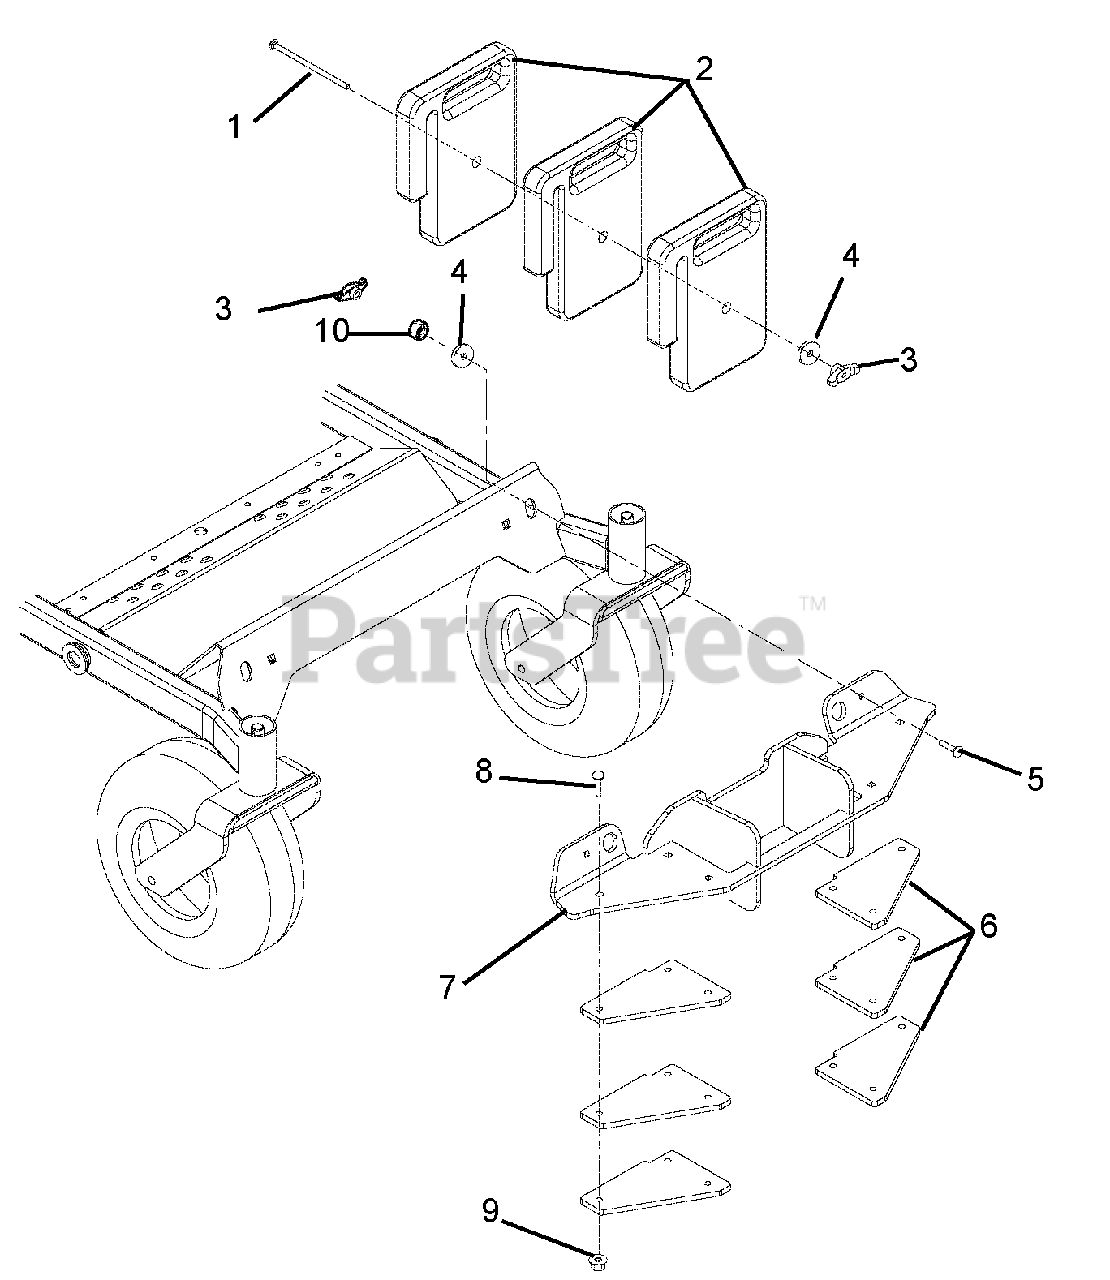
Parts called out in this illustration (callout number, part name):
1	Bolt, Round Head Square Neck .31-18 x 6.50 Grade 5
2	Counterweight
3	Knob, Wing .312-18 UNC (Tool-less hardware option)
4	Washer, Flat Steel .406 x 1.50 x .245
5	Bolt, Round Head Square Neck .31-18 x 1.75 Grade 5
6	Weight, Bagger Plate
7	Weldment, Weight Plate
8	Bolt, Round Head Square Neck .38-16 x 2.00 Grade 5
9	Nut, .38-16 Nyloc Flange
10	Nut, .31-18 Nyloc Flange
